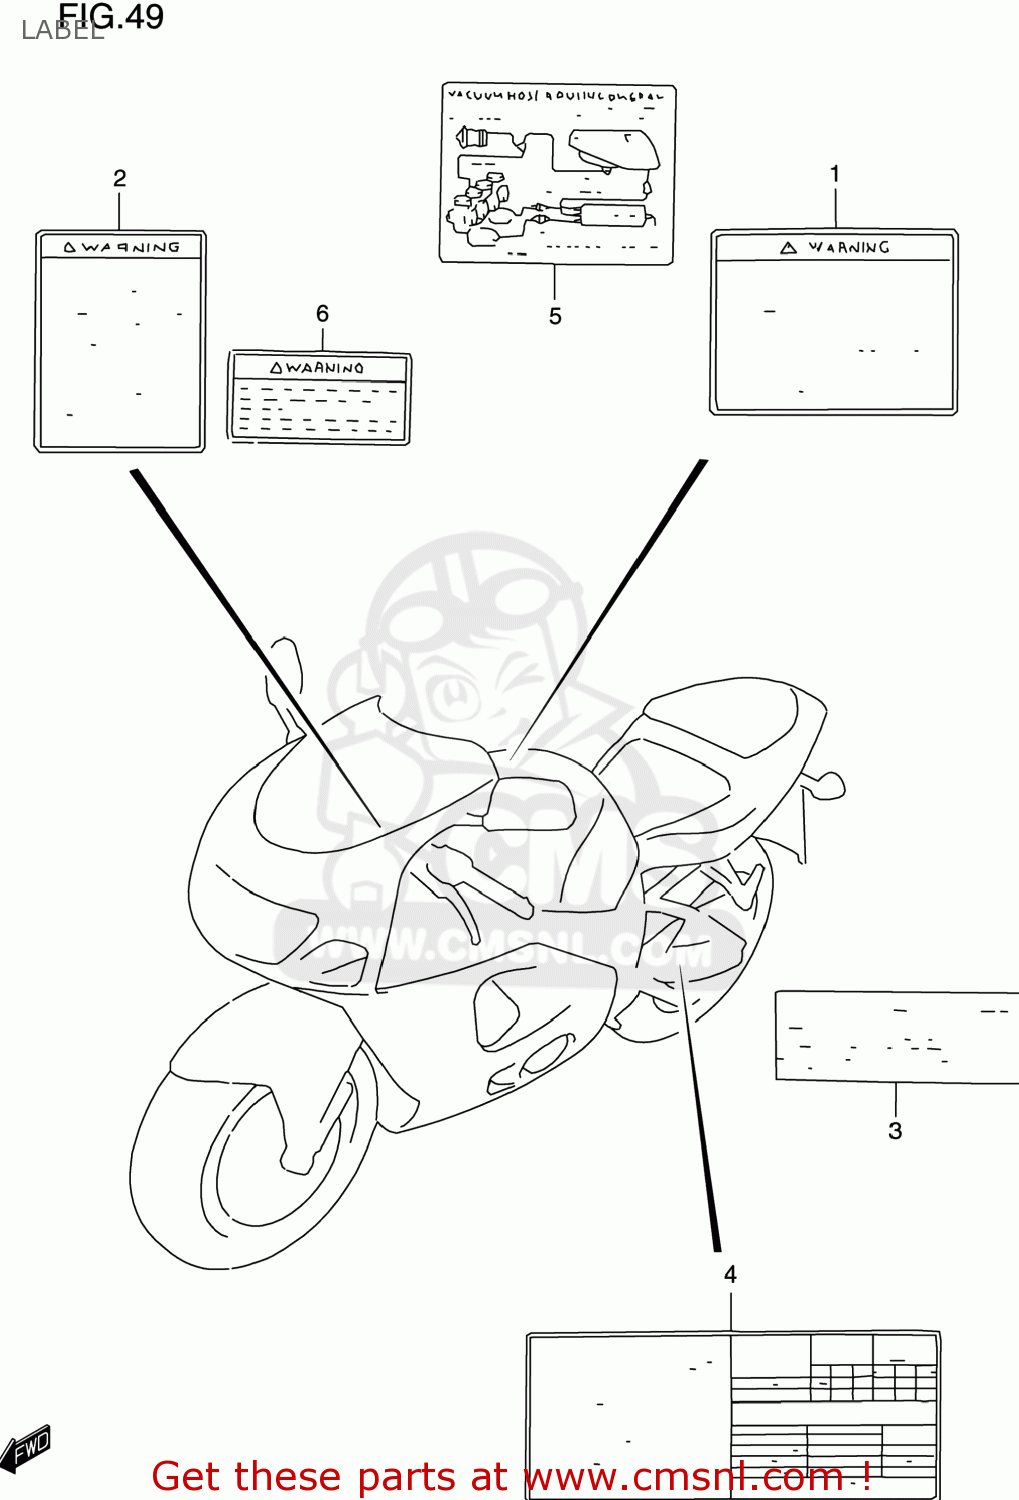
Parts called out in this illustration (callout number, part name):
1	LABEL,GENERAL WARNING
2	LABEL,WARNING SCREEN
3	LABEL (MANUAL NOTICE)
4	LABEL,TIRE INFORMATION
5	LABEL,VACUUM HOSE ROUTING
6	LABEL,WARNING STEERING
7	MANUAL, OWNER'S
